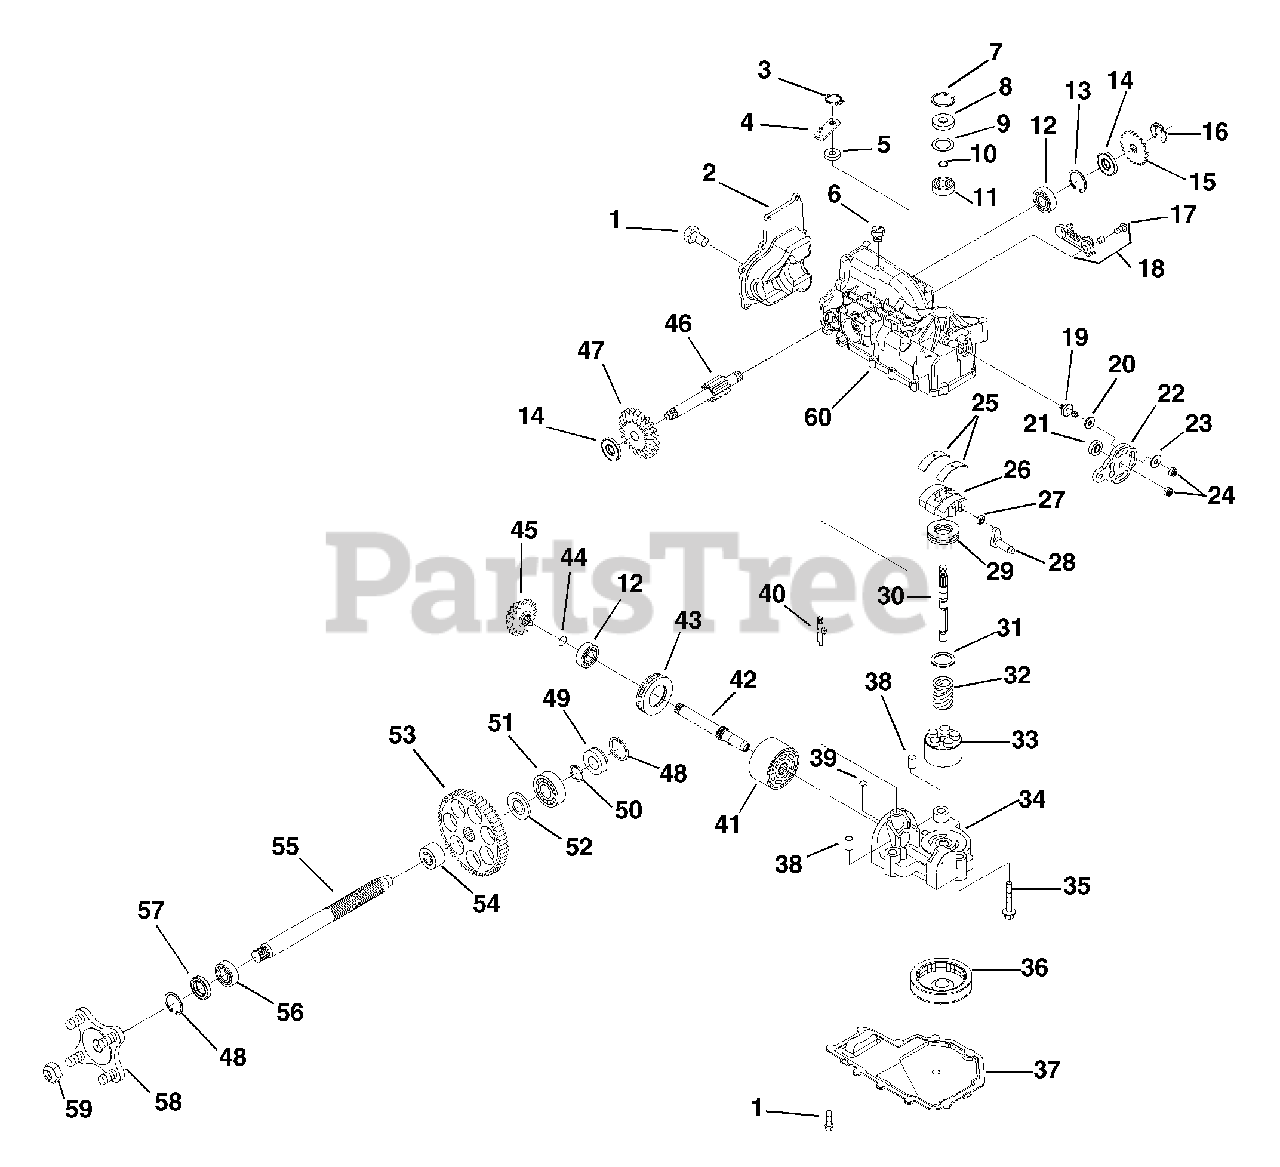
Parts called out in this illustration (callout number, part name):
1	Screw .25-20 x .75
2	Cover-Back
3	Ring-Retaining
4	Arm-Bypass
5	Seal-Lip
6	Plug-Plastic
7	Ring-Retaining
10	Ring-Wire Retaining
11	Bearing-Ball
12	Bearing-Ball
13	Ring-Retaining
14	Seal-Brake Shaft
15	Brake Disc
16	Kit-Retaining Ring
17	Screw-Hex Washer Head 1/4-20 x 7/8
18	Service Assembly-Right Hand Brake Arm
19	Stud-Short 5/16-24
20	Friction Puck
22	Arm-Control
23	Washer
25	Cradle Bearing
26	Variable Swashplate
27	Slot Guide
28	Arm-Trunnion
29	Bearing-Thrust 30 x 52 x 13
30	Shaft-Input
31	Washer-Block Thrust
32	Spring-Block
33	Assembly-Cylinder Block 10cc
34	Assembly-Center Section
36	Filter
37	Housing-Lower
38	Pin-Alignment
39	Bypass Plate
40	Bypass Actuator
41	Assembly-Cylinder Block 21cc
42	Shaft-Motor
43	Bearing-Thrust 42 x 68 x 16
44	Ring-Wire Retaining
45	Gear-Bevel 14T
46	Kit-Brake Shaft
47	Gear-Bevel 19T
48	Ring-Retaining - Axle
49	Seal-Plug - Side
50	Ring-Retaining - Axle
51	Bearing-Ball 20 x 47 x 14
52	Bushing-Axle
53	Gear-Spur 53T
54	Bushing-Axle
55	Shaft-Axle
56	Bearing-Ball 25 x 47 x 12
58	Assembly-Hub
59	Nut-Hex 3/4-16
60	Housing-Upper Assembly
